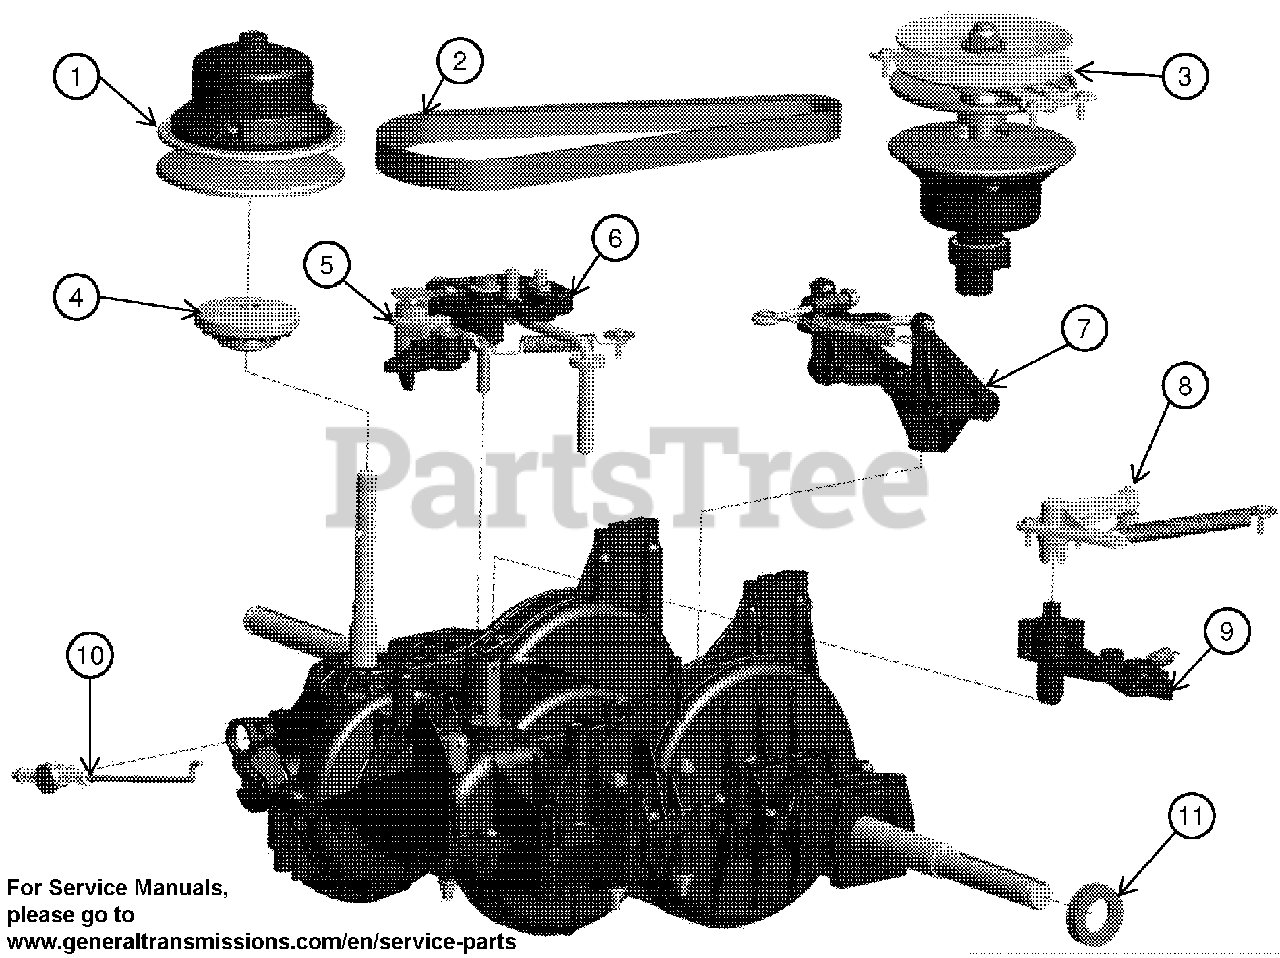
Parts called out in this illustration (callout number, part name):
1	DRIVEN KIT RS800
2	VARIATION BELT
3	DRIVER / ANTI DEBRIS KIT
4	TRANSMISSION KIT
5	CONTROL
7	TRANSMISSION KIT
8	BRAKE KIT
9	BYPASS KIT
10	INVERSION KIT
11	OUTPUT SEAL (QTY 1)
